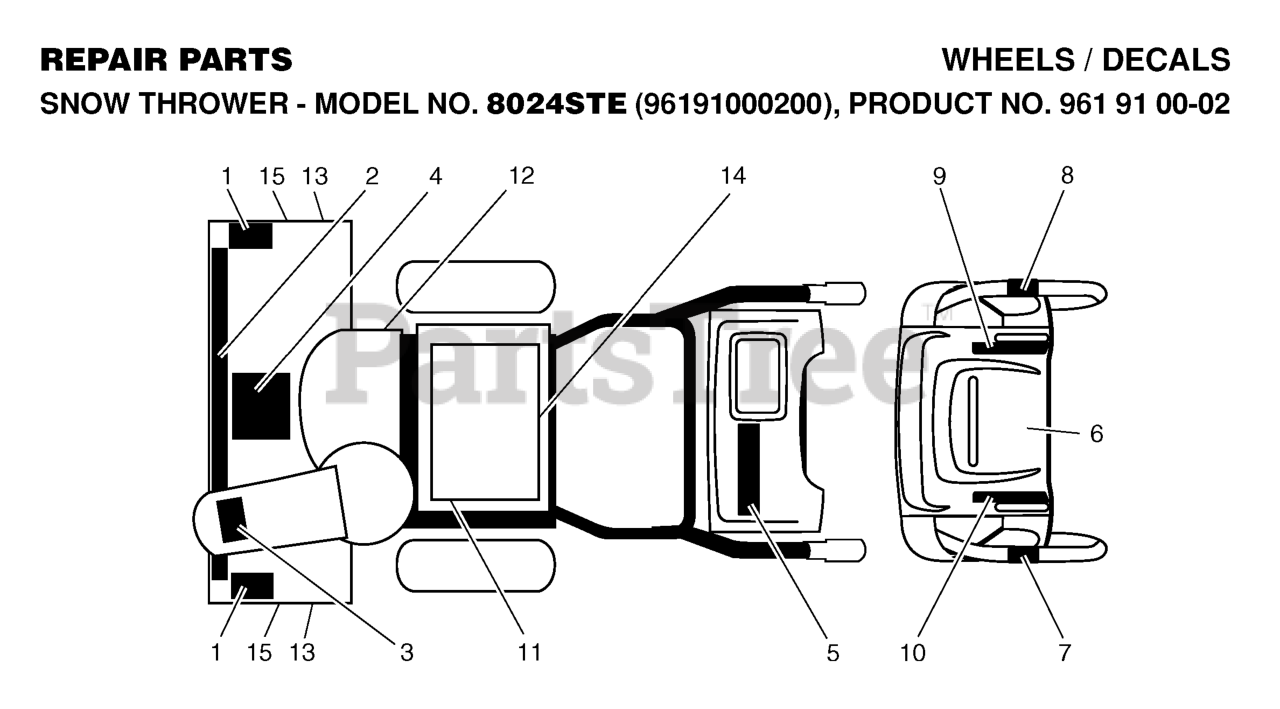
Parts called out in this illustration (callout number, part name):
4	DECAL.AUGER."
6	DECAL.CONSOLE.INSTRUCTION
10	DECAL.REM.DEFLECTOR.LT
12	DECAL.BELT.GUARD.
14	DECAL.FENDER
15	DECAL, HUSQVARNA
